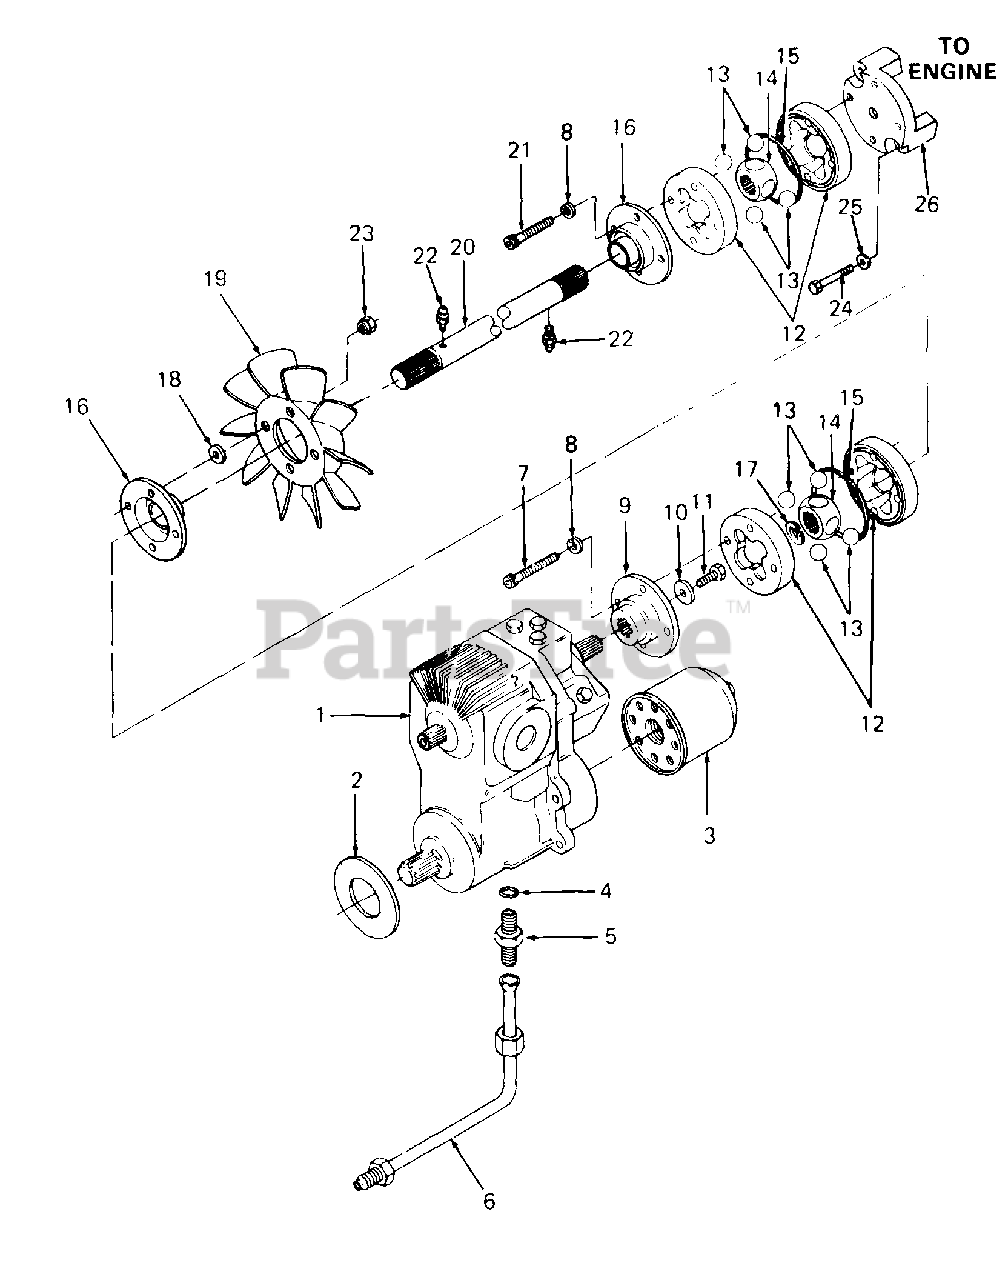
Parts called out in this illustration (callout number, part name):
1	Pump, Hydrostatic
2	Gasket, Front
3	Filter, Oil
4	O-Ring, 5/8 OD Tube
5	Connector, 37 Degree
6	Tube Assy
7	Screw, Socket Hd Cap, 1/4-20 x 2.0 Lg
8	Washer, Lock, 1/4
9	Adapter, Pump
10	Washer, Bell, .265 x .75 x .062 Thk
11	Bolt, Hex Patch, 1/4-20 x 1.0 Lg GR5
12	Coupling, Drive w/0-Ring Groove
13	Ball, Steel, 5/8 Dia Chrome
14	Hub, Drive
15	O-Ring, 2.489 x .070
16	Boot, Coupling
17	Ring, Snap
18	Washer, Flat, .25 x .62 x .052 Thk
19	Fan, 10 Blade Hydro
20	Shaft, Drive, 20.38 Lg
21	Screw, Socket Hd Cap, 1/4-20 x 1.75 Lg
22	Fitting, Grease
23	Nut, Fan, 1/4-20
24	Bolt, Hex Patch, M8-1.25 x 50 MM
25	Washer, Flat, .312 x .750 x .119 Thk
26	Adapter, Drive Shaft
